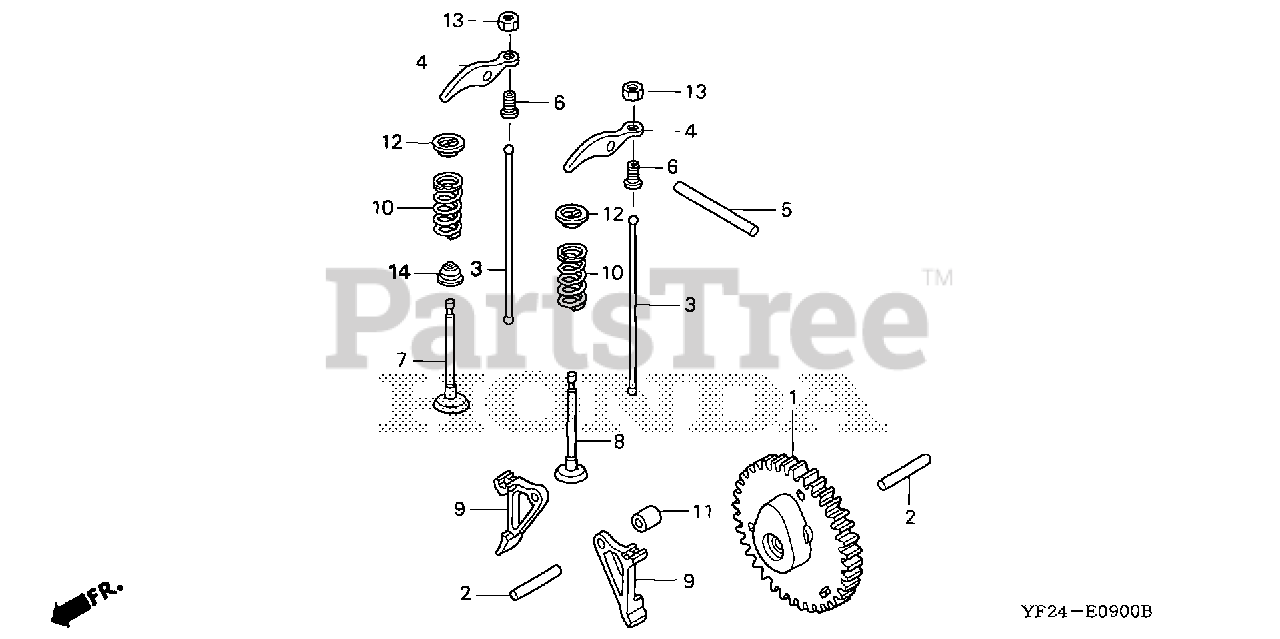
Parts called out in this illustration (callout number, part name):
1	CAMSHAFT ASSY.
2	ROLLER (5X29.8)
4	ARM, VALVE ROCKER
5	ROLLER (4X37.8)
6	PIVOT, ROCKER ARM
7	VALVE, IN.
8	VALVE, EX.
9	LIFTER, VALVE
10	SPRING, VALVE
11	COLLAR, LIFTER
12	RETAINER, VALVE SPRING
13	NUT, TAPPET ADJUSTING
14	SEAL, VALVE STEM
